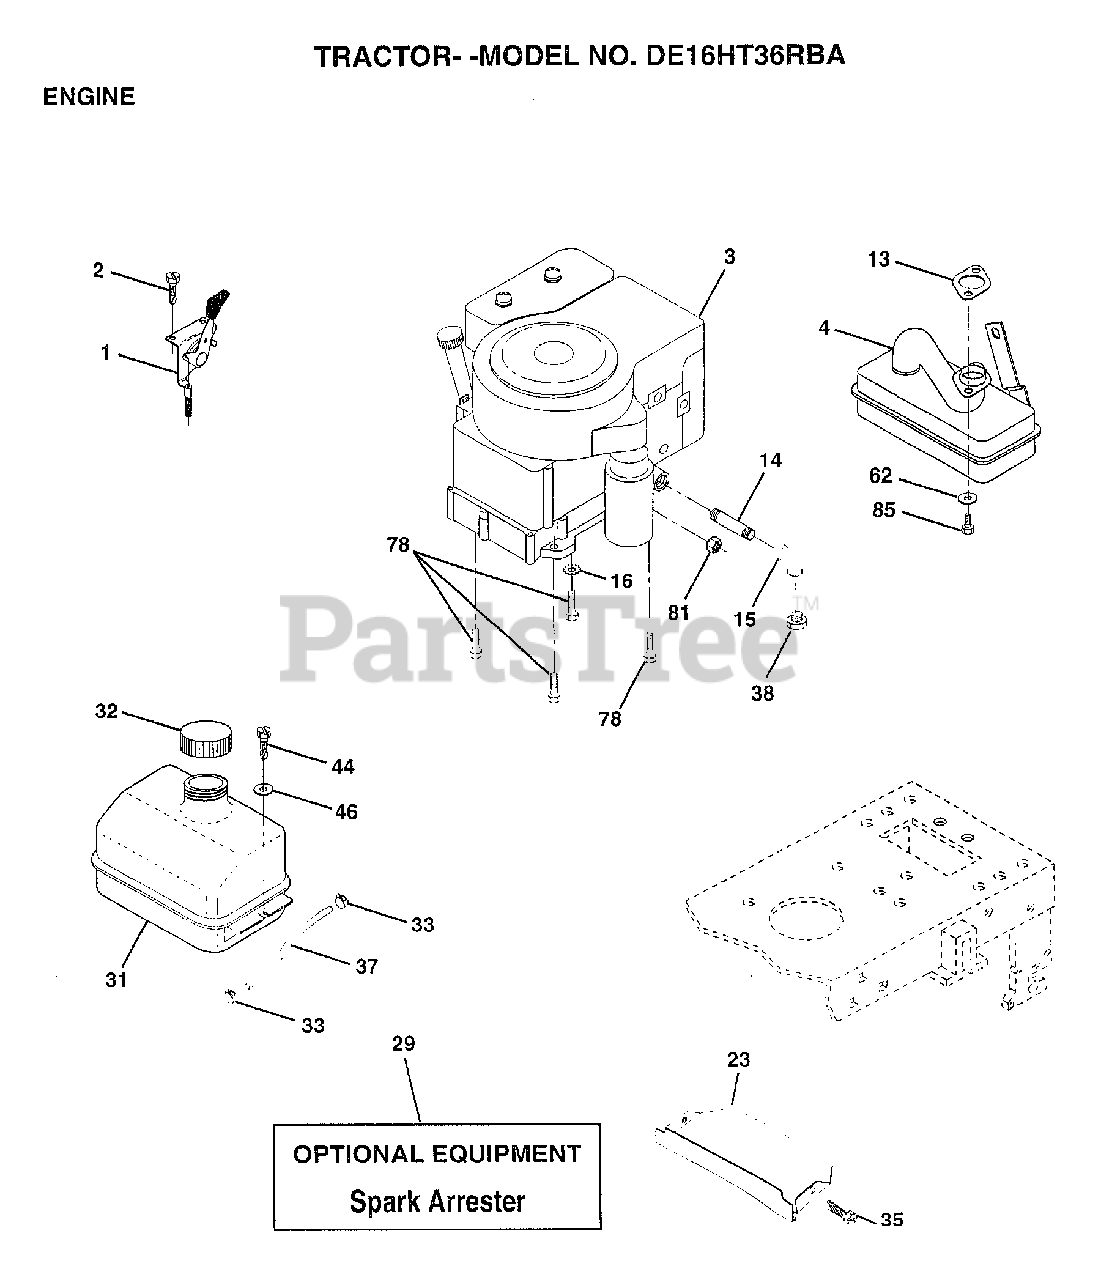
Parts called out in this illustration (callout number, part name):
1	CONTROL THROTTLE
2	SCREW LT
4	MUFFLER
13	GASKET MUFFLE TEC
14	PIPE NIPPLE
15	ELBOW
16	LOCKWASHER
23	SHIELD.BRN/DBR.GD
31	TANK.FUEL.LT.
32	CAP ASM FUEL
33	HOSE CLAMP
35	SCREW
37	LINE FUEL
44	SCREW HEX CRT
46	WASHER
62	LOCKWASHER
78	SCREW
81	NUT
85	SCREW HEX HD CAP
